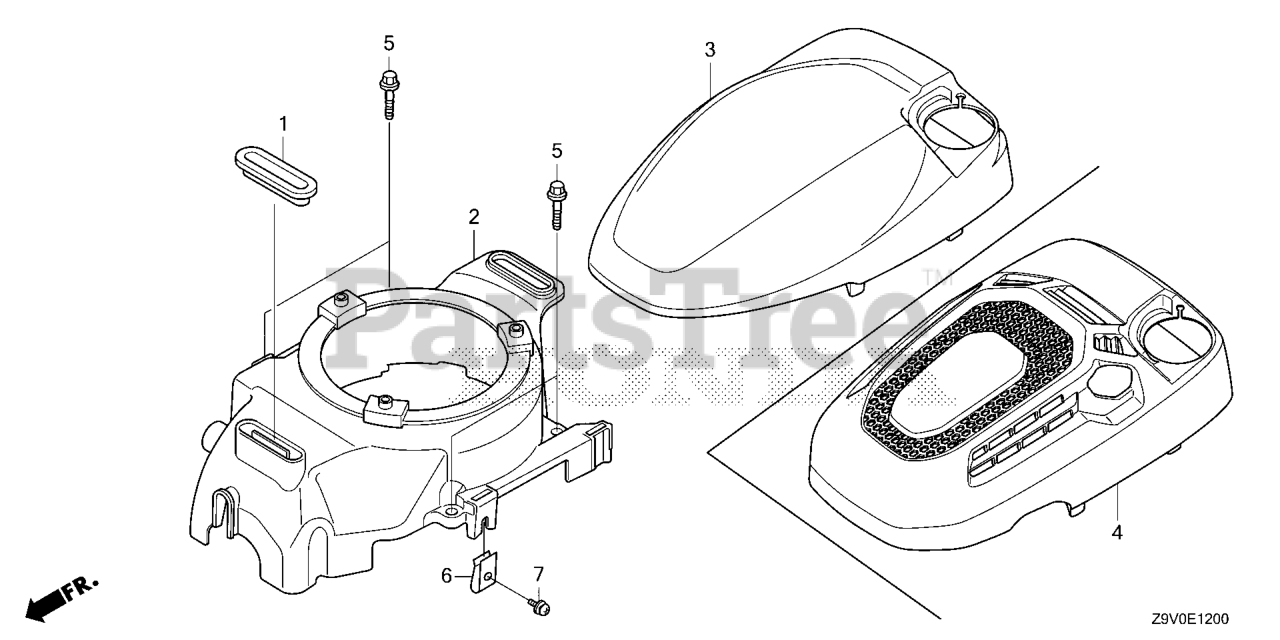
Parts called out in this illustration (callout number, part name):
1	RUBBER A, TANK MOUNTING
2	COVER, FAN
4	COVER, TOP *T104* (RYOBI GREEN)
4	COVER, TOP *NH1* (BLACK)
4	COVER, TOP *T98* (MTD RED)
5	BOLT, FLANGE (6X23)
6	NUT, SPRING (5MM)
7	SCREW-WASHER (5X8)
